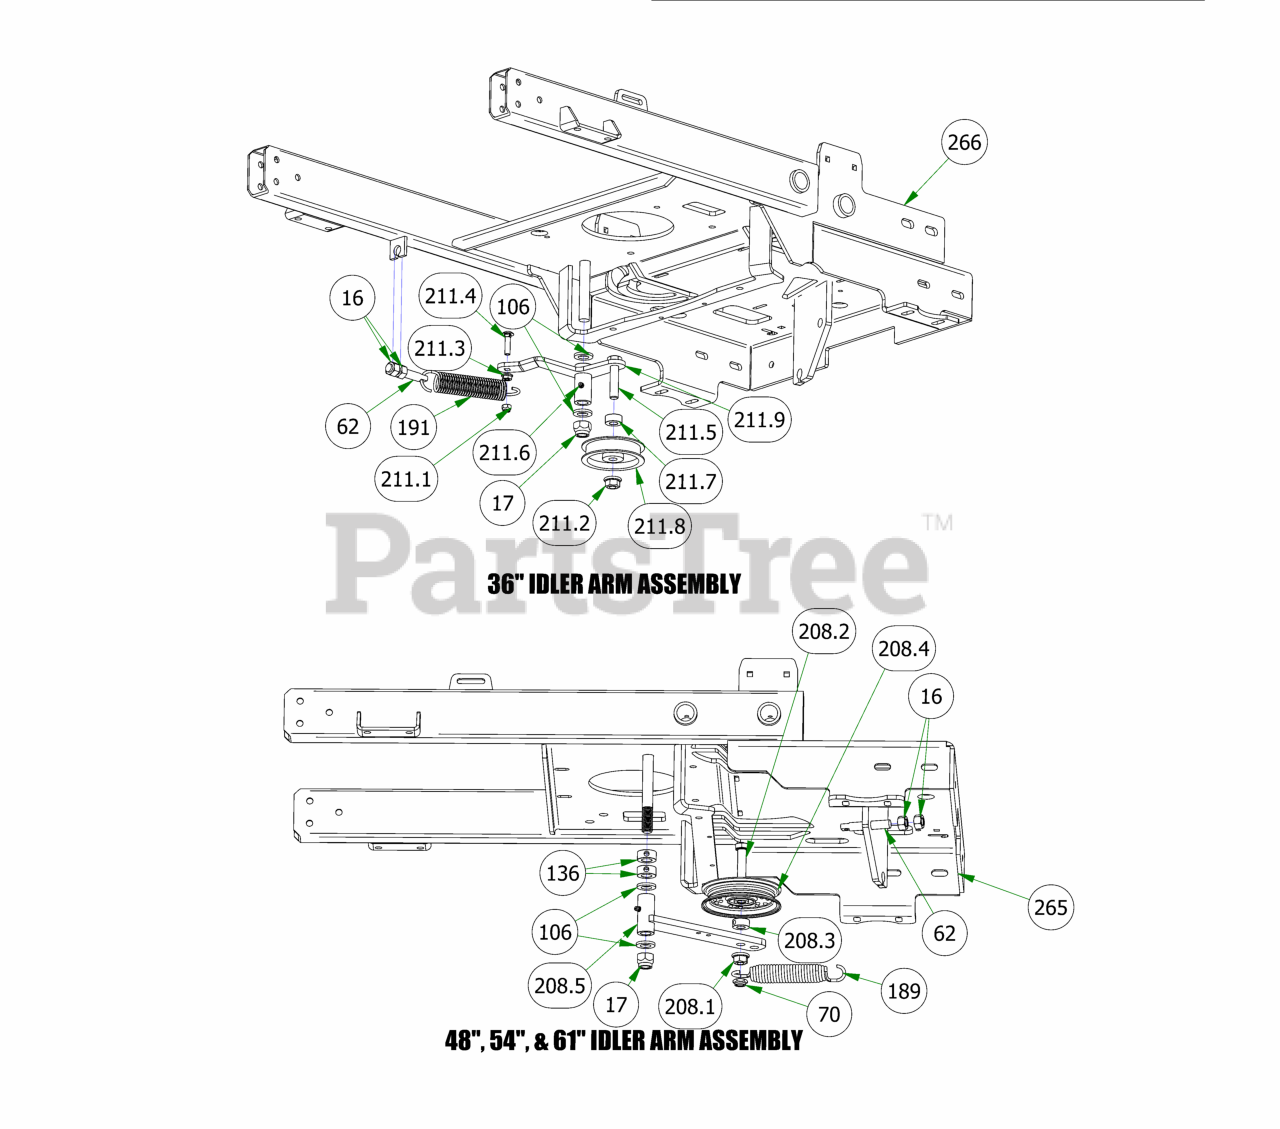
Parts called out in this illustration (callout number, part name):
16	1/2-13 HEX NUT ZINC
17	5/8-11 NYLON INSERT LOCKNUT ZINC
62	All Thread
70	1/2-13 NYLON INSERT JAM LOCKNUT ZINC
106	.635 ID X 1.120 OD X .140 THICK FLAT WASHER NYLON
136	5/8 SOLID SHAFT COLLAR (W/1 SET SCREW) ZINC
189	Deck Idler Spring
191	Deck spring big diameter
208	2019 Stand On Idler Assembly
208.1	1/2-13 NYLON INSERT FLANGE LOCKNUT ZINC
208.2	1/2-13 X 2-3/4 HEX CAP SCREW (GR.5) ZINC
208.3	1/2 SOLID SHAFT COLLAR (W/1 SET SCREW) ZINC
208.4	4 3/4 Idler Pulley - ABFI-76
208.5	Deck Idler
211	2020 36" Stand-On Drive Belt Pulley Assembly
211.1	5/16-18 NYL INS L/N ZC
211.2	1/2-13 NYLON INSERT FLANGE LOCKNUT ZINC
211.3	5/16-18 HEX SERRATED FLANGE NUT HARD/ZINC
211.4	5/16-18 X 1-1/4 CARRIAGE BOLT ZINC
211.5	1/2-13 X 2-1/4 HEX CAP SCREW (GR.5) ZINC
211.6	1/4" Press in Grease Fitting
211.7	1/2 SOLID SHAFT COLLAR (W/1 SET SCREW) ZINC
211.8	3.25 Flat Idler Pulley
211.9	36 Pump Idler Arm Weldment
265	2019 Stand On Frame
266	2020 36" Stand On Frame
